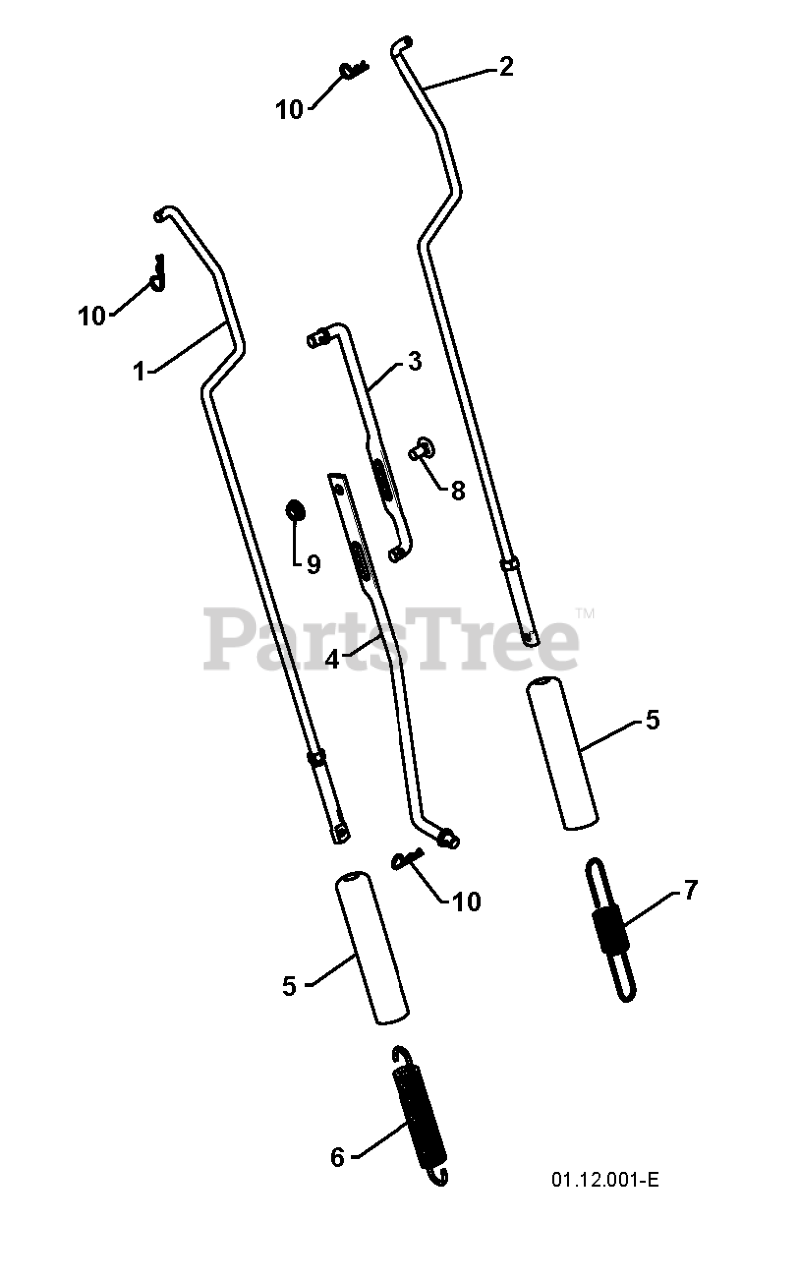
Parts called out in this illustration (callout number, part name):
1	ROD.ASM.IMPELLER
2	ROD.ASM.TRACTION
3	ROD, UPPER SPEED CONTROL
4	ROD, LOWER SPEED CONTROL.SNOW
5	SLEEVE, SPRING
6	SPRING, AUGER CONTROL
7	SPRING, TRACTION DRIVE
8	BOLT
9	NUT.FLANGE.5/16
10	SPRING RETAINER
